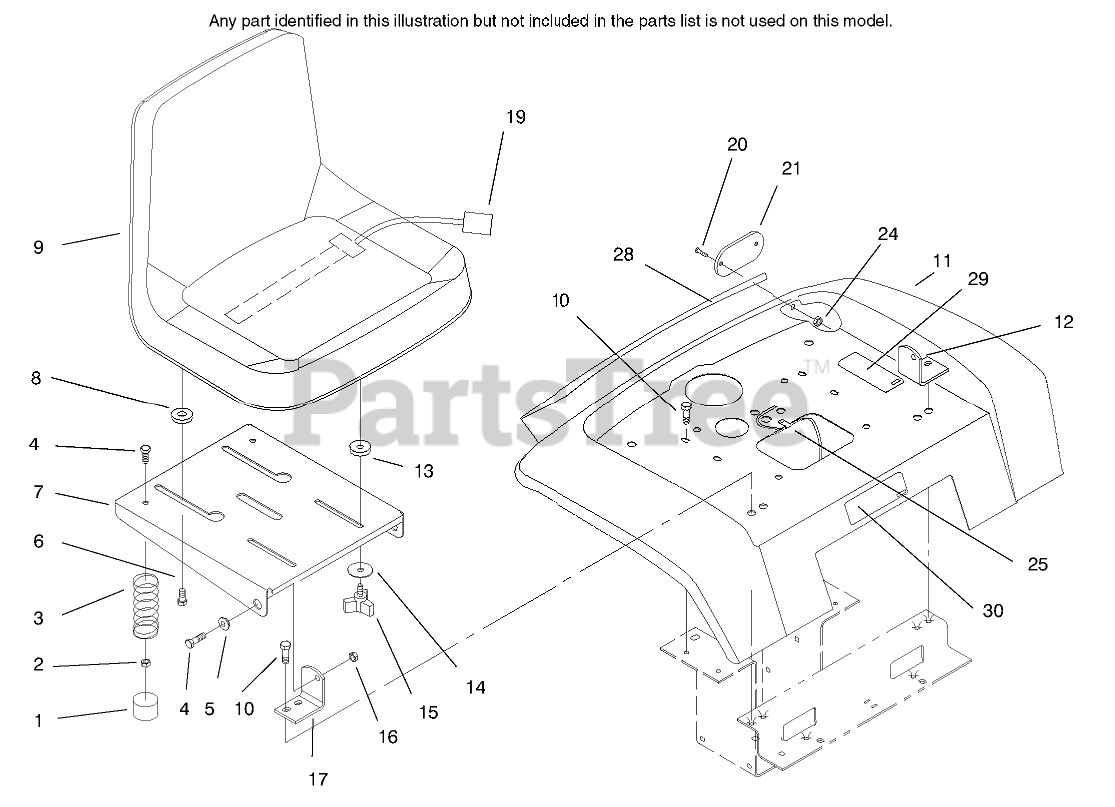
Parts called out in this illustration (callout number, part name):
1	CAP-PROTECTOR
2	NUT-LOCK, NI
3	SPRING-COMPRESSION
4	SCREW-HH
5	BUSHING
6	BOLT-SHOULDER
7	SUPPORT - SEAT (BLACK)
8	SPACER-NYLON
9	SEAT-V-511
10	Bolt
12	BRACKET-PIVOT, LH
13	SPACER-NYLON
14	WASHER
16	NUT-LOCK, NI
17	BRACKET-PIVOT, RH
19	SWITCH-SEAT
20	SCREW-PPH
21	Reflector
24	NUT-LOCK, NI
28	DECAL - REAR FENDER
30	DECAL - USA
